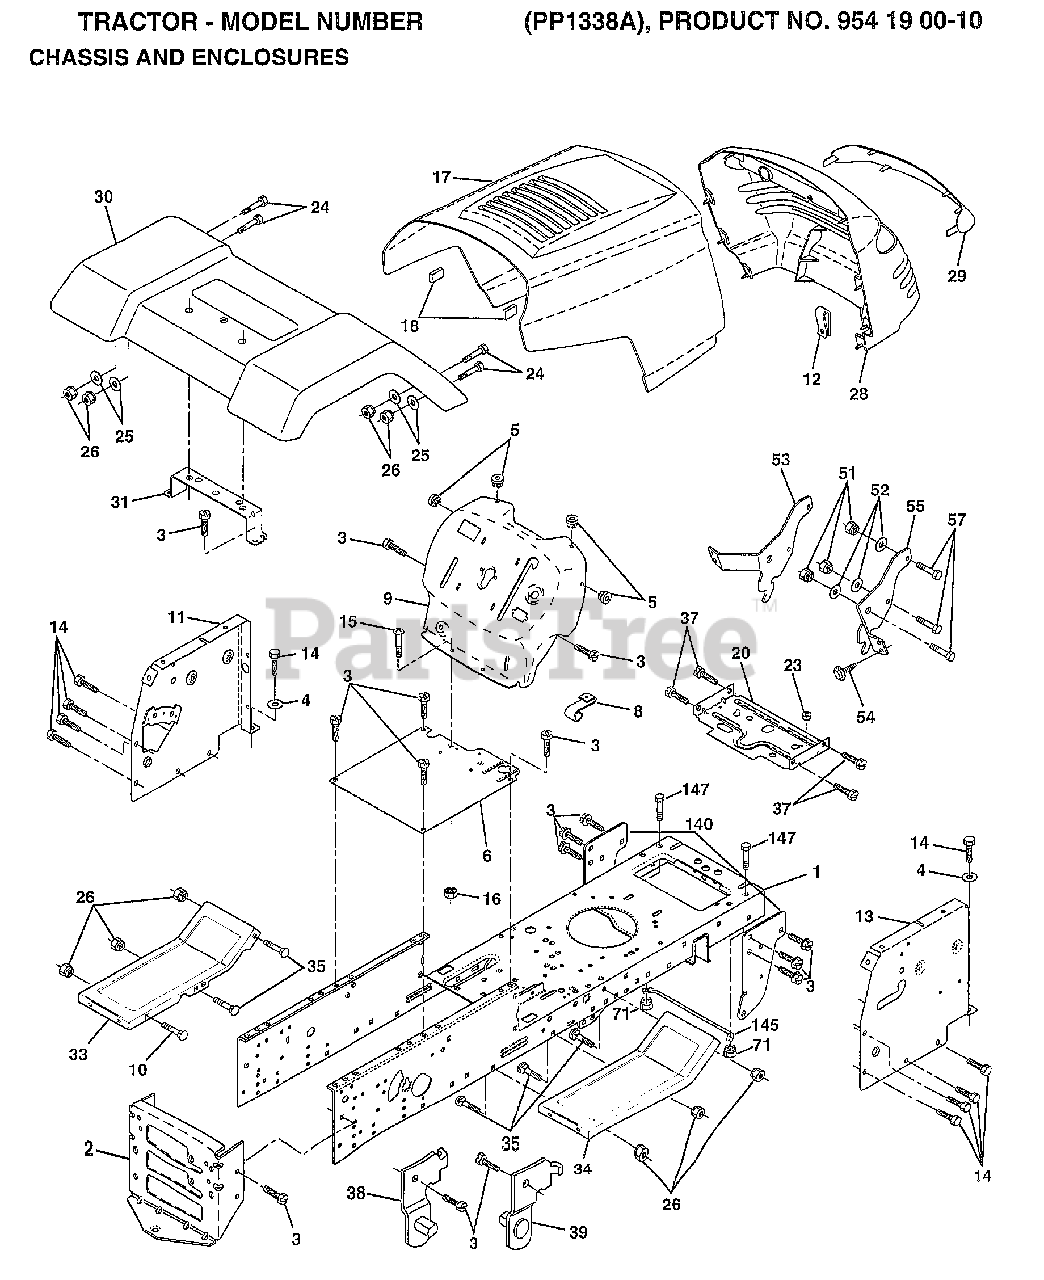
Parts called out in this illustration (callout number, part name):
1	CHASSIS ASM
3	SCREW
4	WASHER
5	BUMPER-HOOD/DASH
6	SADDLE
8	CLIP.RETAINER
9	DASH.SILKSCREENED
11	"PANEL-DASH,LH"
12	CLIP.TINNERMAN
13	"PANEL-DASH,RH"
14	SCREW LT
15	SCREW
20	"PLATE-MTG,BATT/FU"
24	BOLT
25	WASHER
26	NUT
28	GRILLE-MS428
29	LENS GRILLE
30	FENDER PNT LT W
31	BRKT FENDER
33	FOOTREST.LH.LT/GT
34	FOOTREST.RH.LT/GT
35	BOLT
37	SCREW LT
38	BRACKET ASM LH
39	BRACKET ASM RH
51	NUT
52	WASHER
53	BRACKET.GRILLE.LH
55	BRACKET.GRILLE.RH
140	BRKT SUSPENSION
145	"ROD POVOT,CHASSIS"
147	BOLT LT
